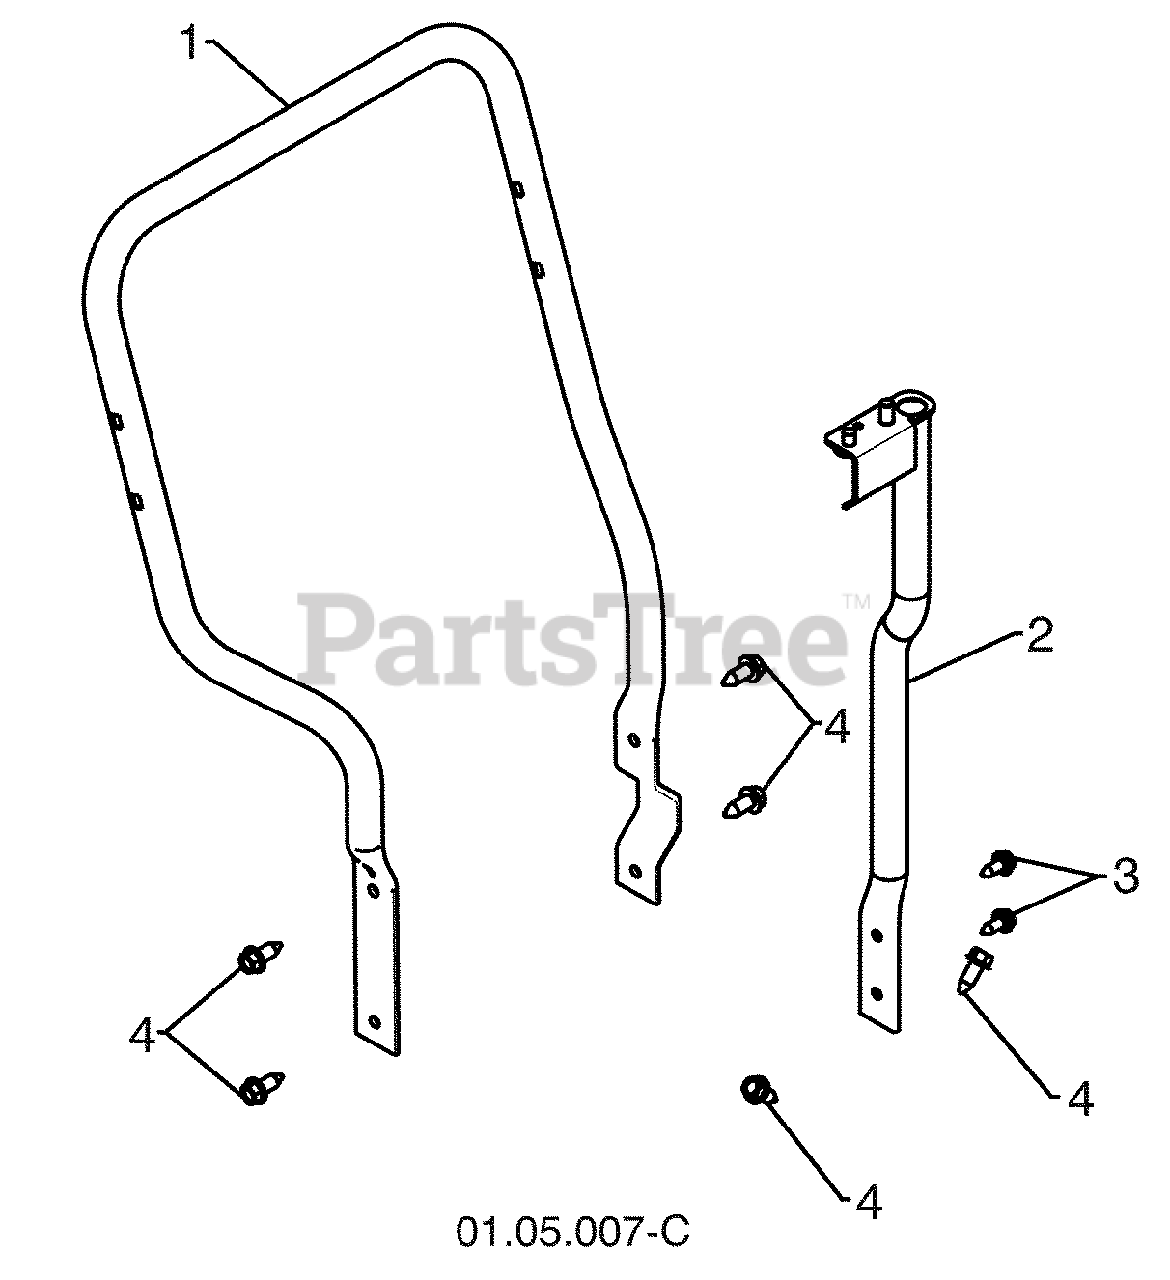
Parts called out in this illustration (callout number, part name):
1	LOWER TUBE GRAY
2	PIVOT SUPPORT
3	BOLT 5/16-18 X .750
4	SCREW 3/8-16 X 1.00
